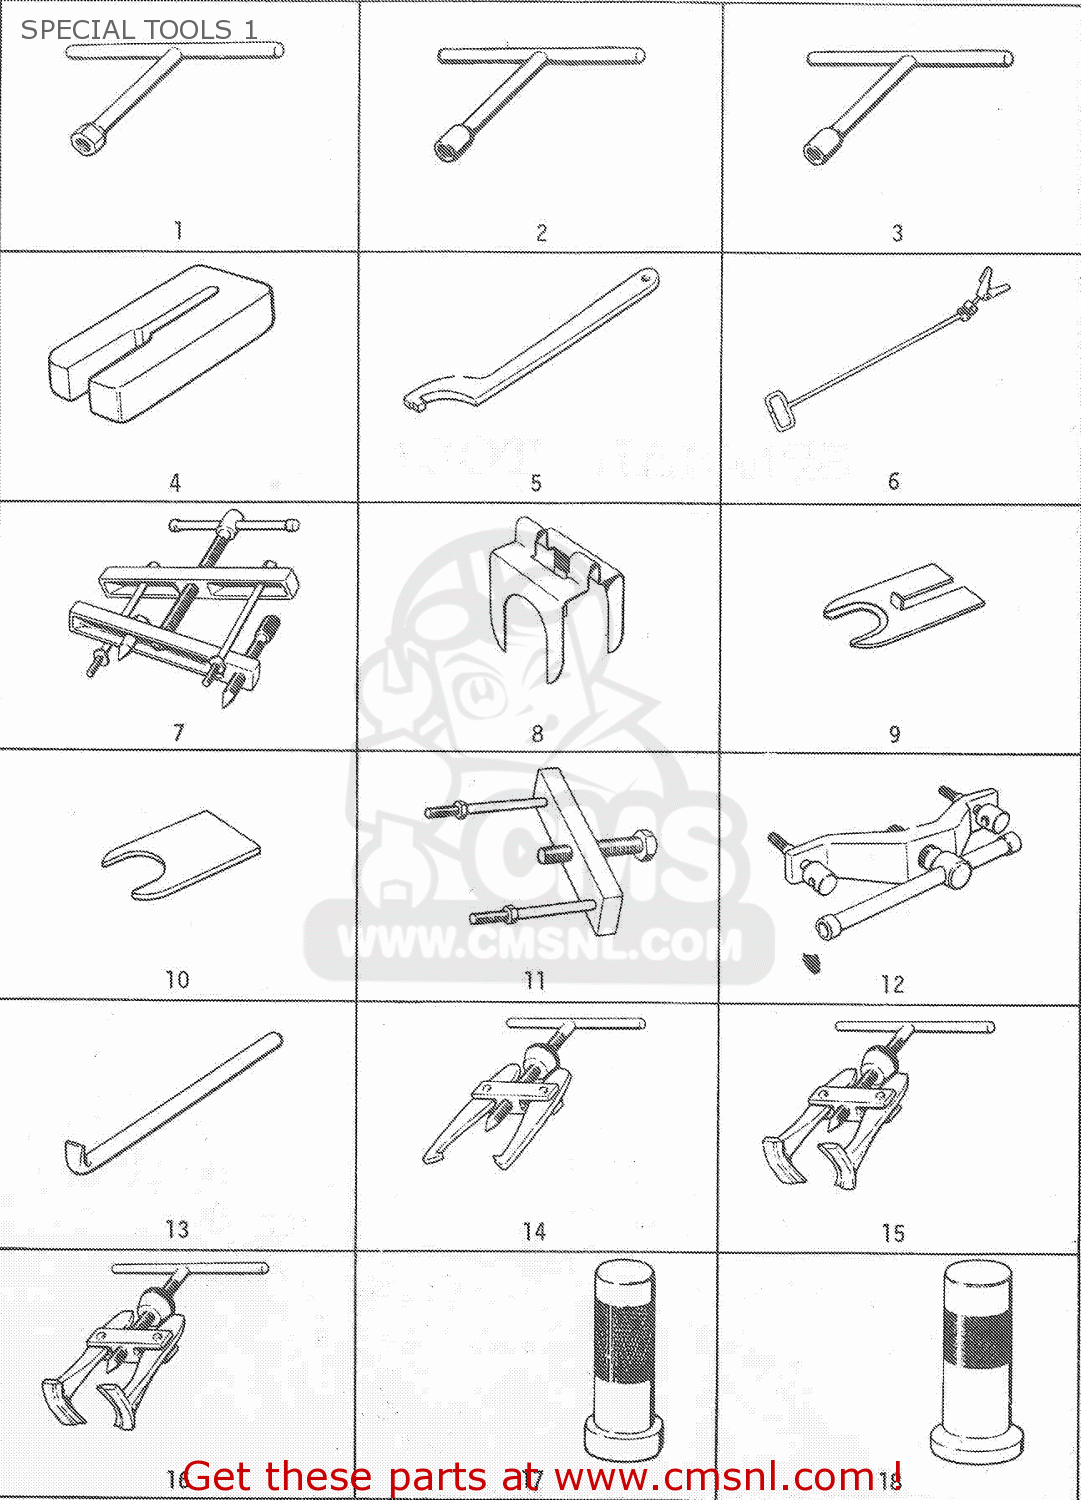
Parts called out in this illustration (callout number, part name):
1	TOOL
2	TOOL
4	PISTON HOLDER
5	UNIVERSAL CLAMP WRENCH
6	EXHAUST PIPE CL
7	CRANKCASE SEPARATING TOOL
13	OIL SEAL,REMOVER
14	BEARING,GEAR PULLER
17	BEARING & OIL SEAL INSTALLING TOOL
18	BRG INSTAL TOO
